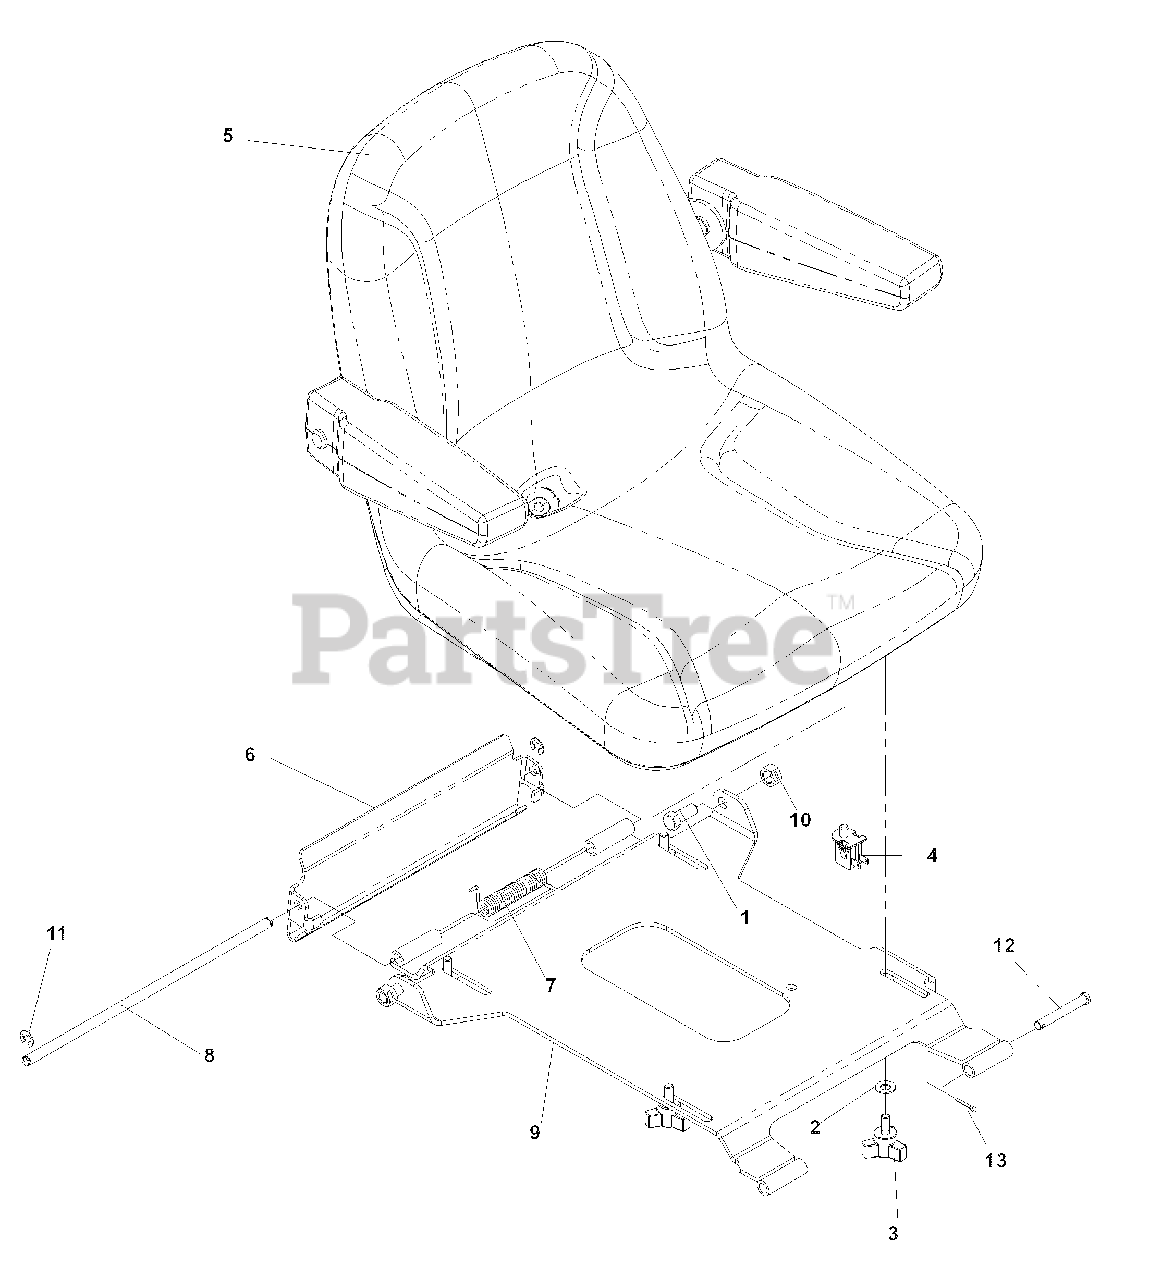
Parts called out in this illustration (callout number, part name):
1	HCS, 7/16-14 x 1
2	WASHER, 3/8, SPRING, SPEC
3	KNOB W/STUD
4	SEAT SWITCH
5	SEAT W/ARMREST
6	SEAT LATCH BRACKET
7	TORSION SPRING
8	SEAT LATCH ROD
9	SEAT MOUNT
10	NUT, 7/16-14, CNTRLCK, GR A
11	RING-RETAINING
12	CLEVIS PIN
13	PIN, COTTER, 1/8 x 3/4
